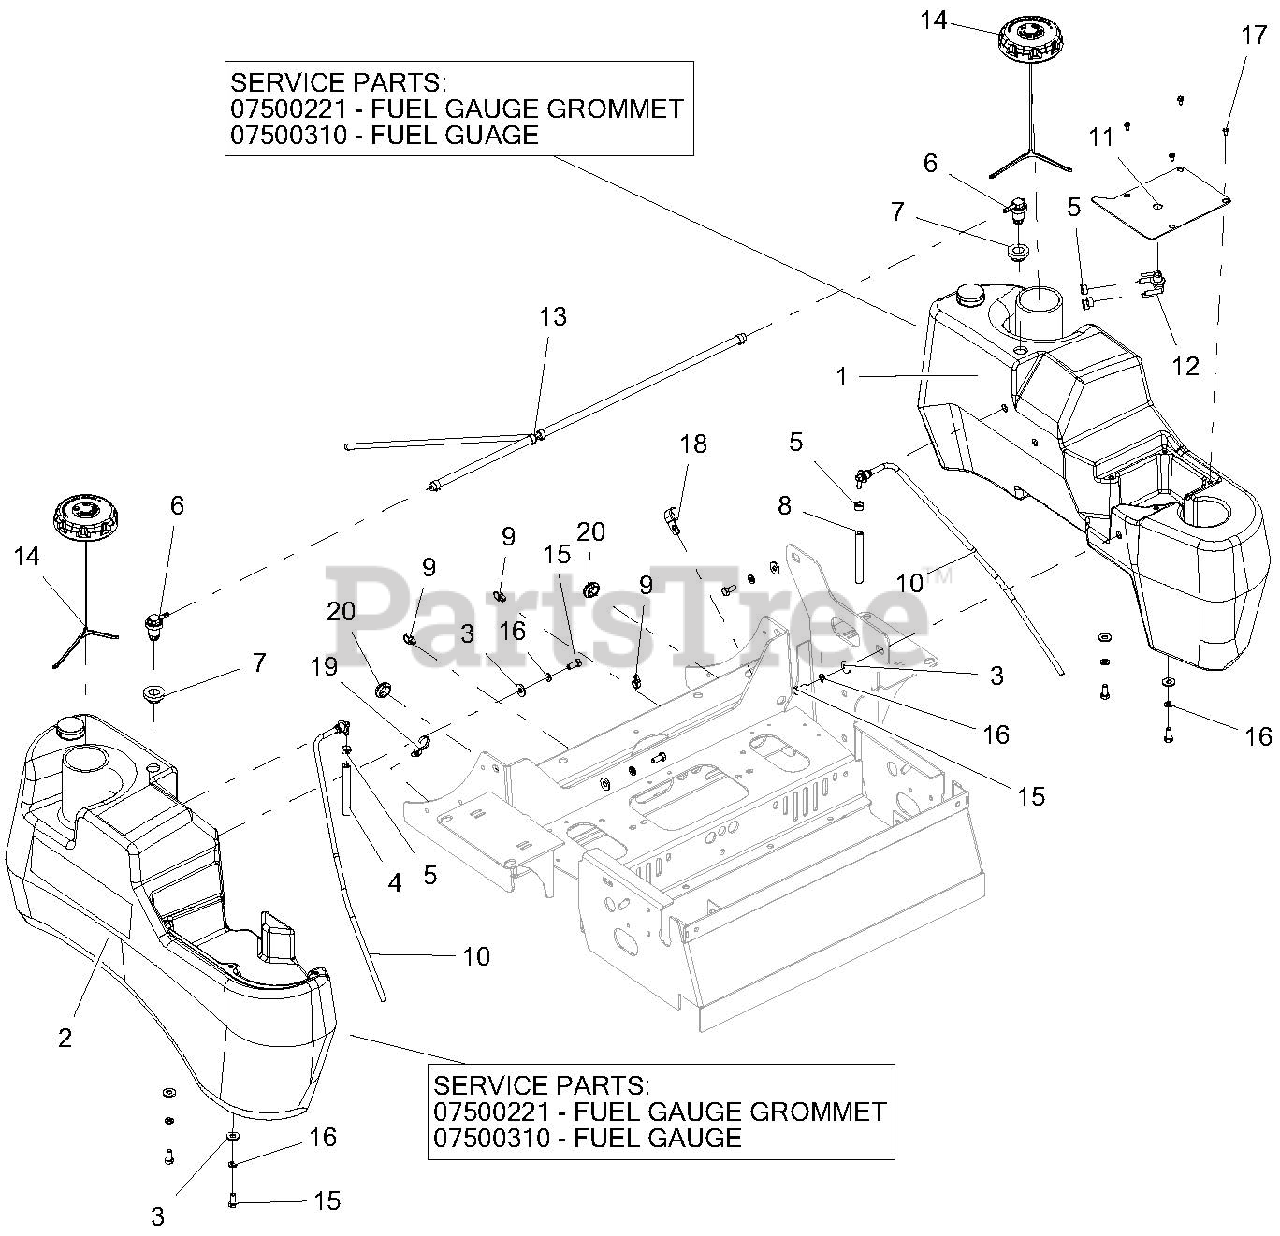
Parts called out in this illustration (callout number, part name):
1	ASSY-LH LARGE FUEL TANK W/MECH GAUGE-GAS
1	FUEL GUAGE GROMMET
1	FUEL GUAGE
2	ASSY-RH LARGE FUEL TANK W/MECH GAUGE-GAS
2	FUEL GUAGE GROMMET
2	FUEL GUAGE
3	WSHR-FL-STL.38X.875X.083 YWZC
4	.25 LOW-PERM GAS HOSE 54.00" LG - RH TANK TO VALVE
5	CLAMP, FUEL LINE
6	VALVE, COMBINATION
7	GROMMET, REMOTE VENT NITRILE
8	.25 LOW-PERM GAS HOSE 19.00" LG - LH TANK TO VALVE
9	CLIP, ROUTING
10	ASM, LARGE TANK FUEL PICKUP
11	PLATE, FUEL VALVE MOUNTING-RED
12	VALVE, FUEL
13	PT400, FUEL LINE ASSEMBLY
14	CAP, FUEL VENT-IN AUTOLOCK
15	BLT-HEX .31-18X.75 GR5 YWZC
16	WSHR-LK .31X.078 REG YWZC
17	SCR-MCH 10-24X.38 HWHSTAINLESS
18	CLAMP, CUSHIONED STEEL .75
19	CABLE TIE W/ TREE
